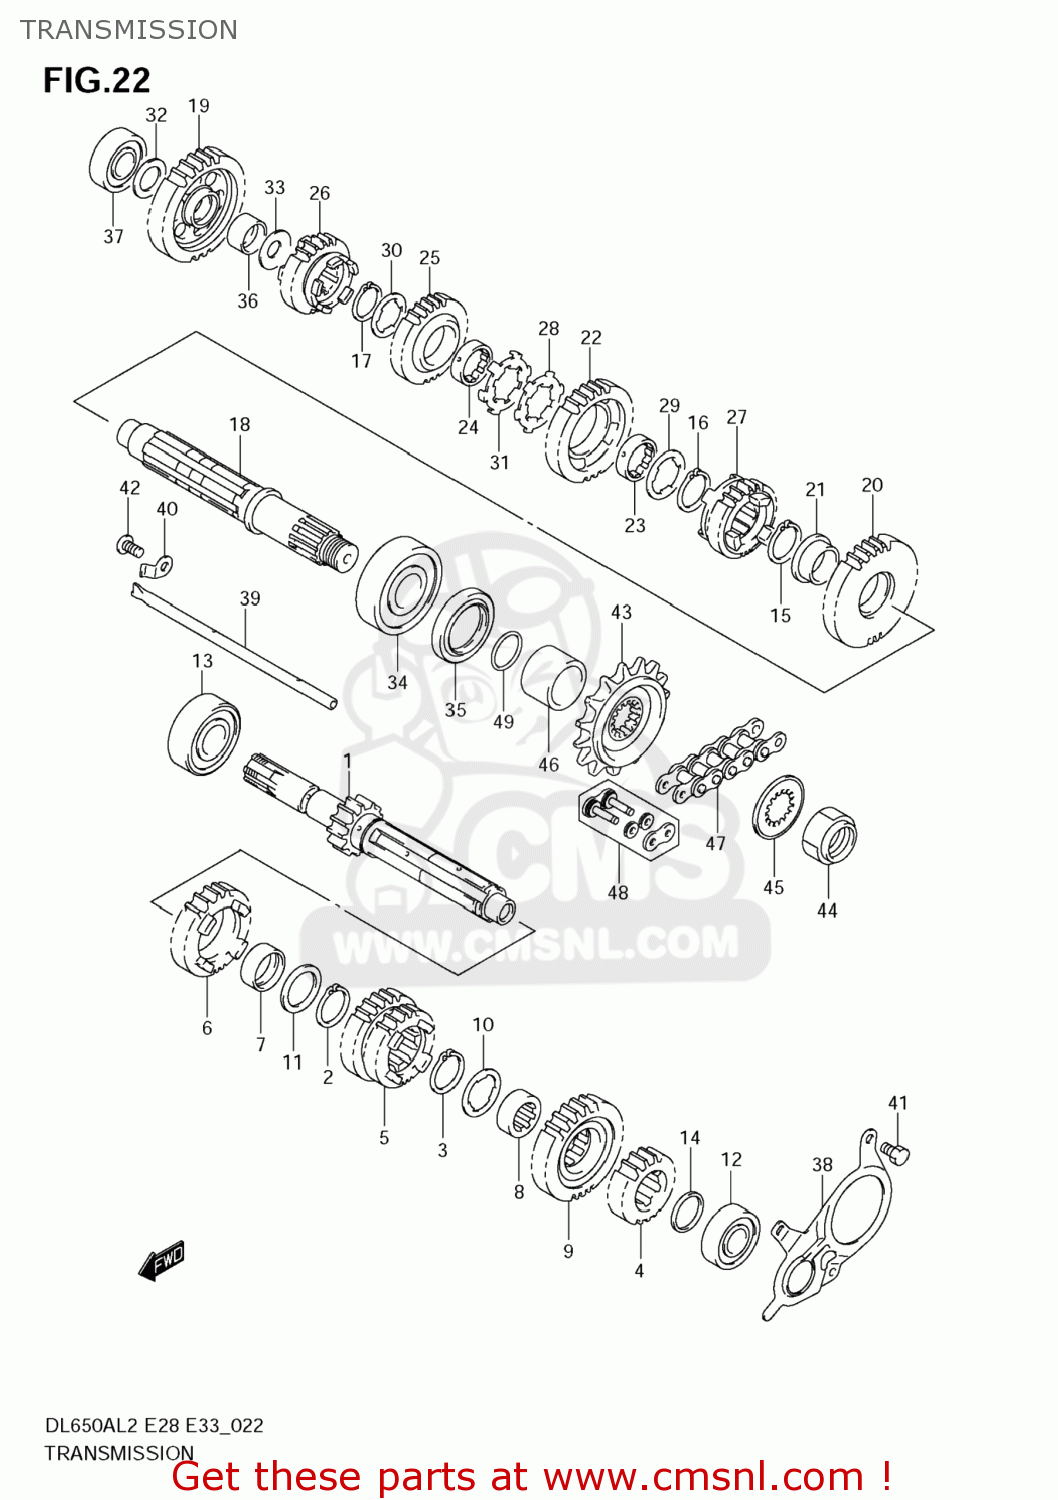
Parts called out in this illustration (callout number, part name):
1	SHAFT,COUNTER
2	CIRCLIP
3	CIRCLIP
4	GEAR,2ND DRIVE
5	GEAR,3RD & 4TH DRIVE
6	GEAR,5TH DRIVE(NT:26)
7	BUSH
8	BUSH,6TH DRIVE GEAR
9	GEAR,6TH DRIVE(NT:27)
10	WASHER,LOCK
11	SHIM(25X34X1)
12	BEARING(17X40X12)
13	BEARING(20X52X15)
14	CIRCLIP
15	CIRCLIP
16	CIRCLIP
17	CIRCLIP
18	SHAFT,DRIVE
19	GEAR,1ST DRIVEN
20	GEAR,2ND DRIVEN
21	BUSH,2ND DRIVEN GEAR
22	GEAR,3RD DRIVEN
23	BUSH,DRIVEN GEAR
24	BUSH,DRIVEN GEAR
25	GEAR,4TH DRIVEN
26	GEAR,5TH DRIVEN
27	GEAR,6TH DRIVEN
28	WASHER,LOCK
29	WASHER,LOCK
30	WASHER,LOCK
31	WASHER
32	SHIM(17X28X1)
33	SHIM(20X30X1)
34	BEARING(25X62X17)
35	SEAL,OIL(36X50X6)
36	BUSH(20X24X13)
37	BEARING(17X40X12)
38	RETAINER,DRIVE SHAFT OIL SEAL
39	GUIDE,T/M OIL
40	RETAINER,TRANSMISSION OIL
41	BOLT
42	SCREW
43	SPROCKET,ENGINE(NT:15)
44	NUT
45	WASHER,LOCK
46	SPACER,ENGINE SPROCKET
47	CHAIN,DRIVE
48	JOINT SET,DRIVE CHAIN
49	O RING(D:2.4,ID:23.7)
